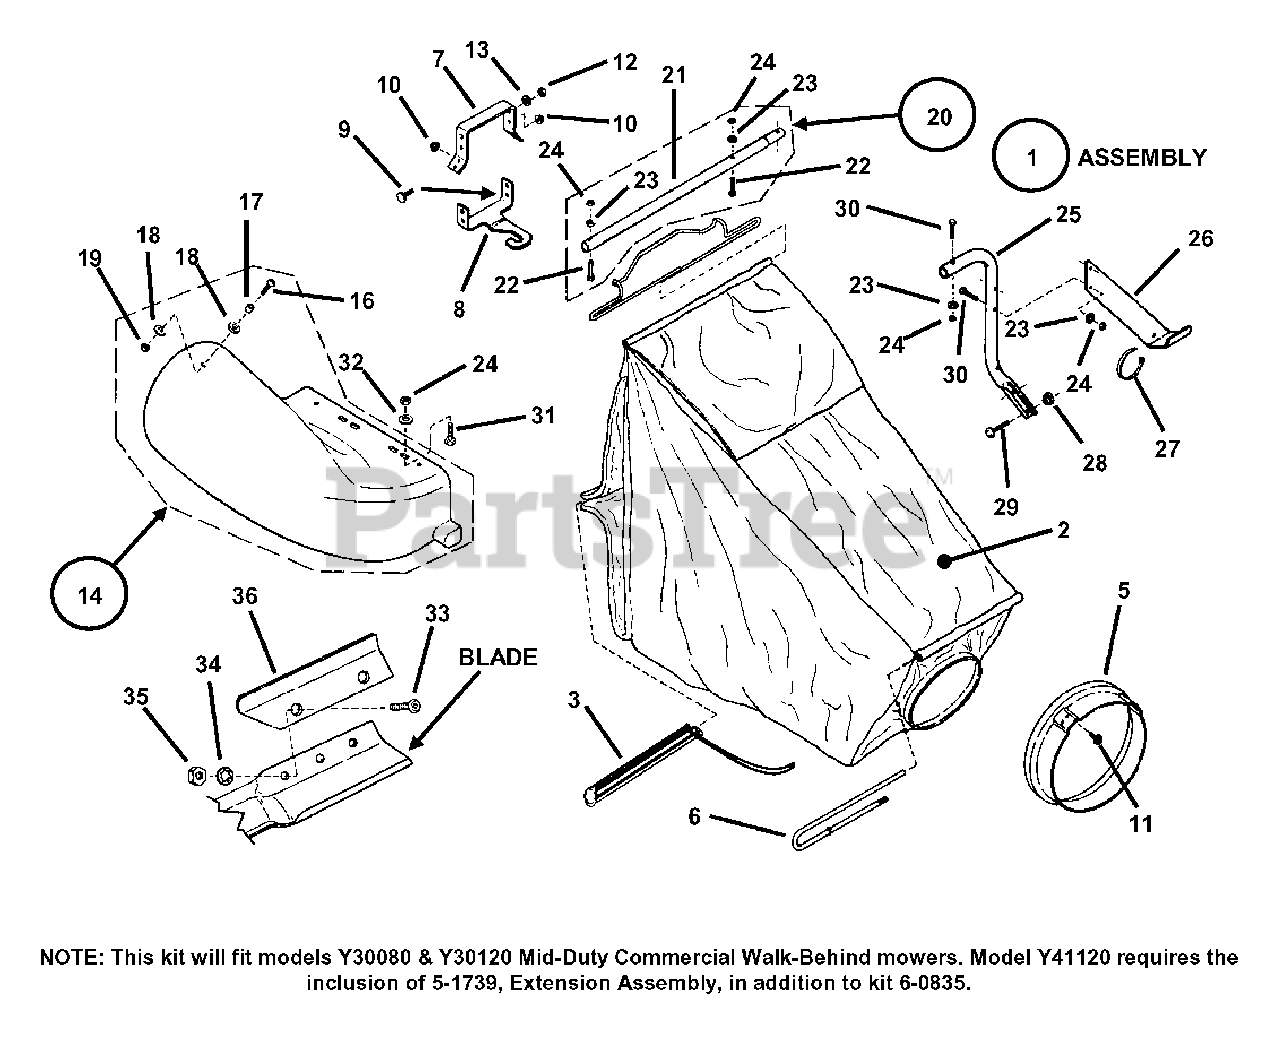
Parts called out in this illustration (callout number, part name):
1	ASS'Y., Bag
2	BAG, Grass
3	SLIDER, Grass Bag
5	ADAPTER, Bag, front
6	WIRE, Bag, Front
7	ADAPTER, Handle
8	LATCH, Chute
9	BOLT, 1/4-20 x 5/8" Carr.
10	NUT, 1/4-20 Hex Flange
11	BOLT, 1/4-20 x 3/4" Carr.
12	NUT, 3/8-24 Hex
13	WASHER, 3/8" Int. Tooth Lock
14	ADAPTER ASS'Y
16	SCREW, 1/4-20 x 3/4" Rd. Hd.
17	SPACER
18	WASHER, 5/16" Flat
19	NUT, 1/4-20 Hex Center Lock
20	SUPPORT ASS'y, Bag, Rear
21	TUBE, Rear Support, Bag
22	BOLT, 1/4-28 x 1-1/4" Hex
23	WASHER, 1/4" Lock
24	NUT, 1/4-28 Hex
25	SUPPORT TUBE, Rear Bag
26	BRACKET, Support
27	CABLE-TIE
28	ROLLER
29	BOLT, 5/16-18 x 2-1/2" Carriage
30	SCREW, 1/4-28 x 1-3/8"
31	SCREW, 1/4-28 x 3/4" Hex
32	WASHER, 1/4" Flat
33	SCREW, 5/16-24 x 21/32"
34	WASHER, 5/16" Int'l. Tooth
35	NUT, 5/16-24 Hex
36	AIR LIFT
